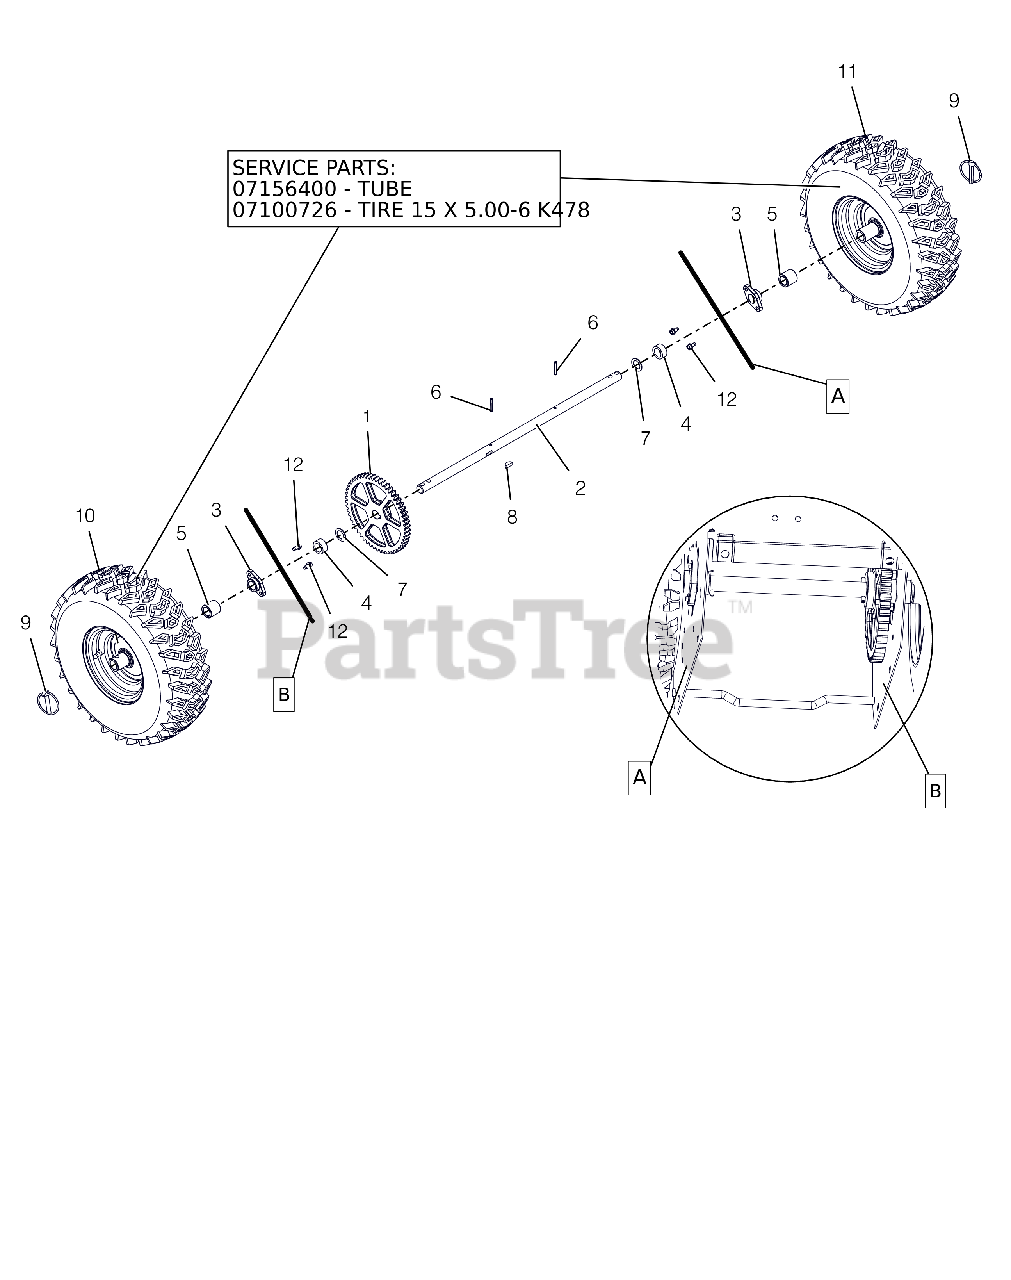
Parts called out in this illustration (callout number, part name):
1	SPUR GEAR, 54T .75ID X 6.75PD
2	AXLE, COMPACT 920,XXX 15" TIRE
3	BSHG .75X1.125X.65
4	BSHG-SLV .766 X 1.125 X .500
5	BSHG-SLV .75X1.12X1.062 NYL BK
6	PIN-ROLL .188X1.25
7	WSHR-FL-STL.754X1.125X.062YWZC
8	KEY-WDRF .25X.750X.313 SAE91
9	PIN-LOK .31X1.75
10	TIRE/WHEEL,RH 15X5.00-6 PIN T2
11	TIRE/WHEEL,LH 15X5.00-6 PIN T2
12	TUBE 15 X 5.00-6
12	TIRE, 15X5.00-6 K478
13	SCR-TAP .25-20X.50 HWH TR YWZ
